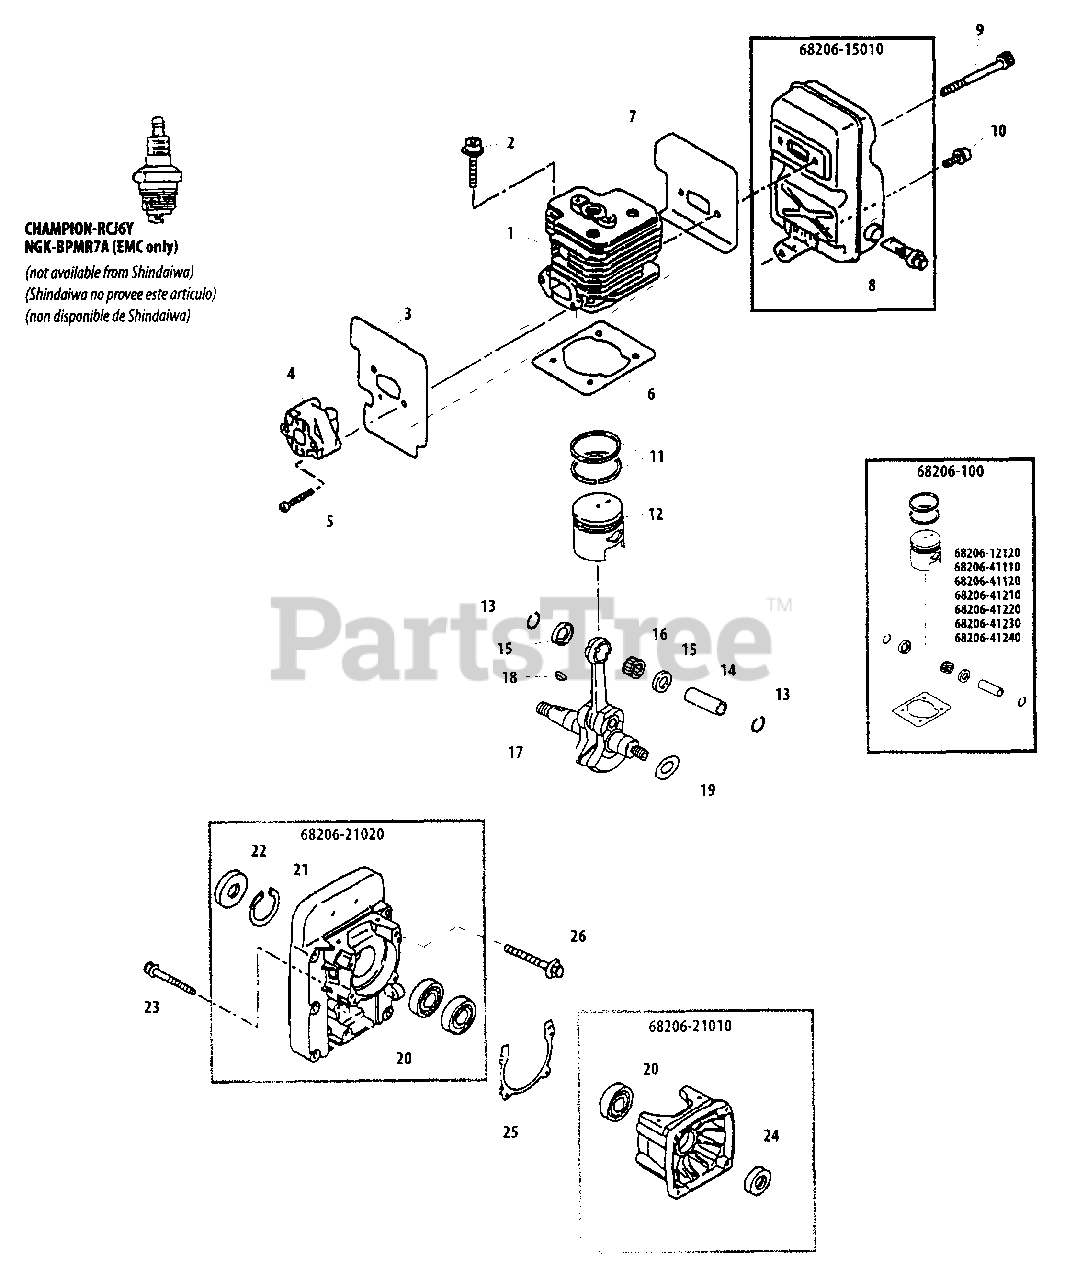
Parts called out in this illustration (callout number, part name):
1	CYLINDER
2	BOLT M5×22
3	SHIELD, HEAT
4	INSULATOR
5	SCREW M5×35
6	GASKET, CYLINDER
7	GASKET, MUFFLER
8	SCREEN, SPARK ARRESTER
9	BOLT M6×70
10	BOLT, FLANGE M6×12
11	RING, PISTON
12	PISTON
13	RING, SNAP
14	PIN, PISTON
15	WASHER, THRUST
16	BEARING, NEEDLE
17	CRANKSHAFT
18	KEY
19	SHIM
20	BEARING, BALL
21	RING, SNAP
22	SEAL, OIL
23	BOLT 5×30
24	SEAL, OIL
25	GASKET
26	BOLT, ADHESIVE M6×40
68206-100	PISTON KIT
68206-15010	MUFFLER ASSY
68206-21010	CRANKCASE ASSY - REAR
68206-21020	CRANKCASE ASSY - FRONT
